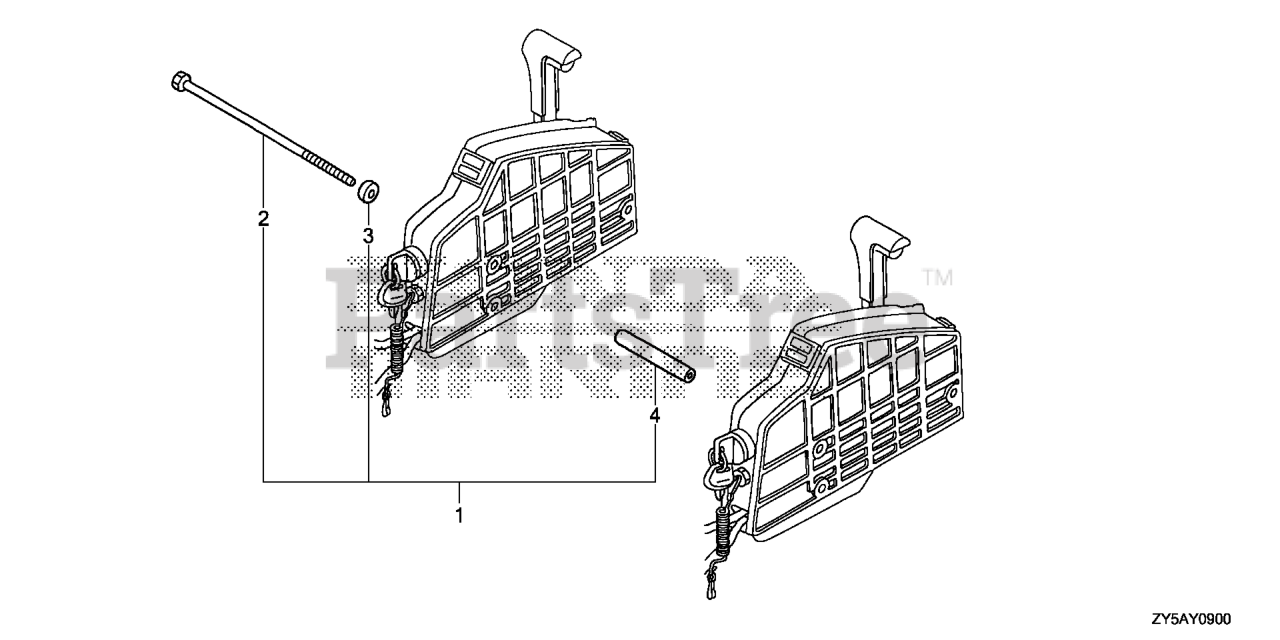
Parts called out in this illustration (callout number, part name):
1	BOLT KIT, SIDE REMOTE CONTROL
2	BOLT, SPECIAL (6X220)
3	COLLAR, DISTANCE (A)
4	COLLAR, DISTANCE (B)
